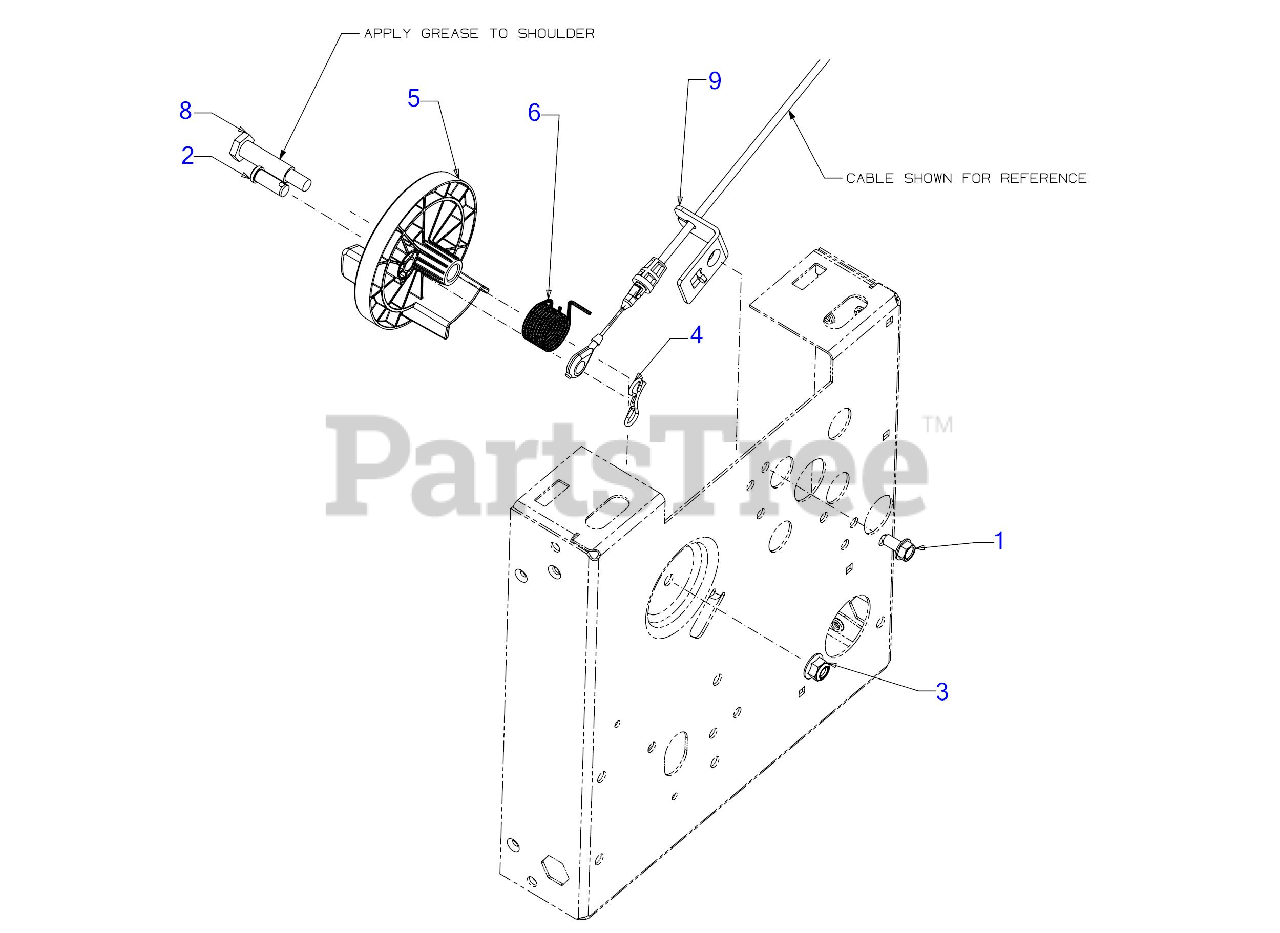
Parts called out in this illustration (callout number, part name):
1	SCREW 5/16-18 x .750
2	CLEVIS PIN .375 x .969
4	PIN:COTTER
5	LUG ACCTUATOR ATTACHMENT
6	TORSION SPRING
8	SHOULDER BOLT .498 x 1.635:3/8-16
9	BRACKET-PTO CABLE FLEX
